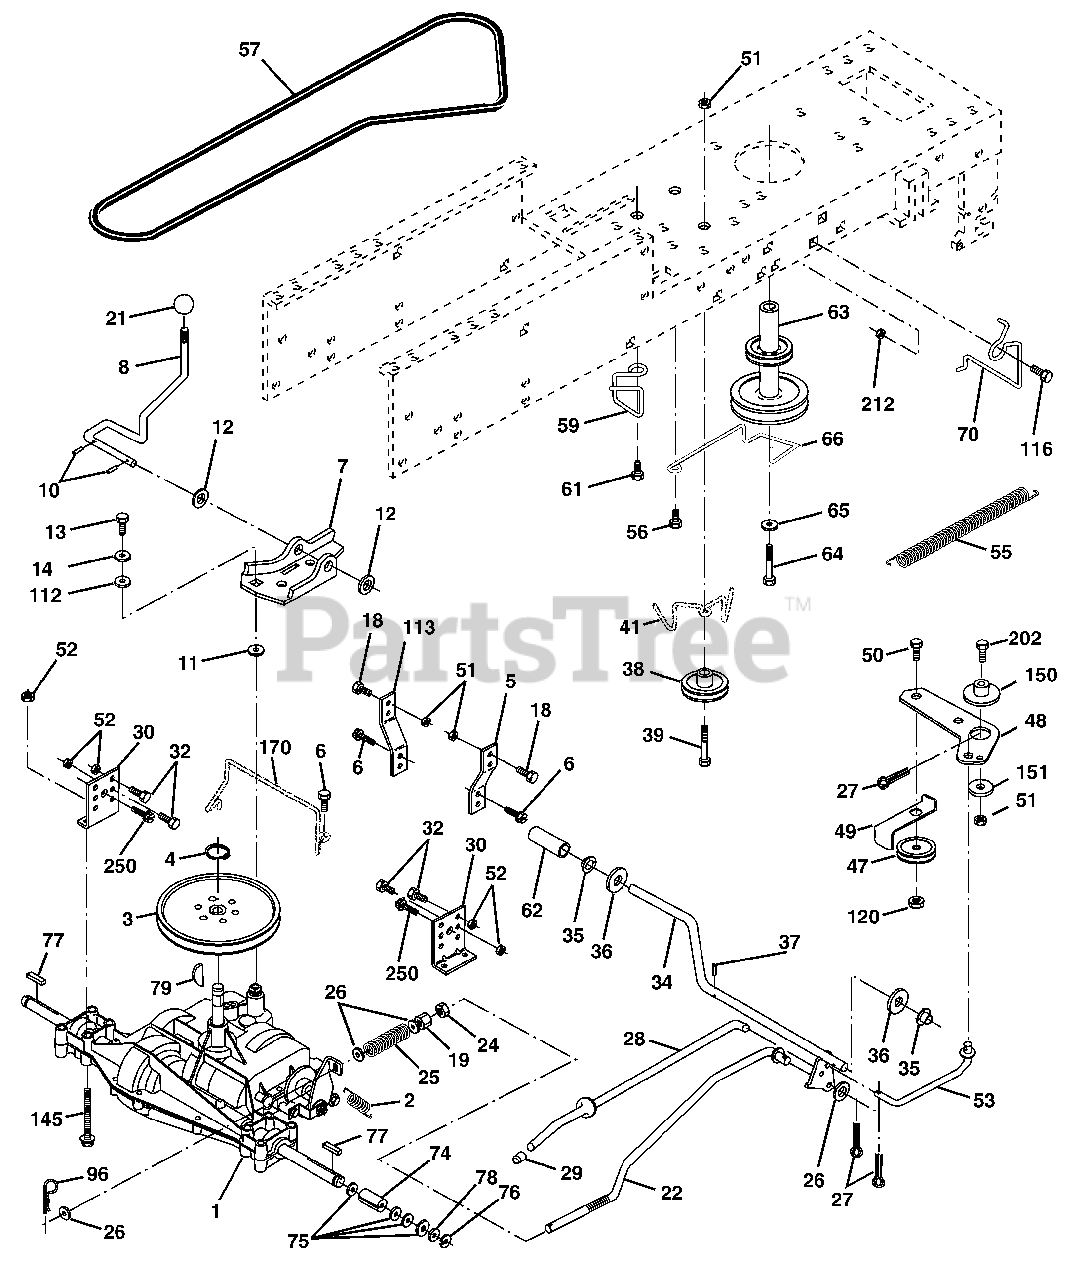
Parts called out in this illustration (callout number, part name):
2	Spring Extension Brake
3	Pulley Transaxle 18" tires
4	Ring Retainer # 5100-62
5	Strap Torque Rh Pnt Blk
6	Screw 5/16-18 X 3/4
7	Bracket T/A Saddle Shift
8	Rod Shifter Black(dana)
10	Pin,Cotter
11	Washer Plate Shf 388 Sq Hole
12	Washer 15/32 X 3/4 X 16ga
13	Bolt 1/4-28 UNF Gr. 8 W/Patch
14	Washer
18	Bolt Fin Hex 3/8-16 UNC x 1 Gr. 5
19	Nut
21	Knob Rd 1/2-13 Plstc Thds Blk
22	Rod Brake Lt
24	Nut
25	Spring Rod Brake 2 00 Zinc
26	Washer
27	Pin
28	Rod Brake Parking
29	Cap Parking Brake
30	Bracket Transmission
32	Bolt
34	Shaft Asm Pedal Foot
35	Bearing Nylon Blk 629 Id
36	Washer
37	Roll Pin
38	Pulley Idler Composite
39	Bolt Fin Hex 3/8-16 Unc x 3
41	Keeper Belt Idler
47	Pulley Idler V Groove Plastic
48	Bellcrank Clutch
49	Retainer Belt Style Spring
50	Bolt
51	Nut
52	Nut
53	Link Clutch 7 66
55	Spring Return Clutch 6 75
56	Screw 3/8-16 x 1-1/4
57	V-belt Ground Drive 95
59	Keeper Belt Chassis Span Ctr.
61	Screw 3/8-16 x .875
62	Cover Pedal Blk Round
63	Pulley Engine
64	Bolt, Hex 7/16-20 x 4 Grade 5
65	Washer, Lock, Hvy Hlcl Spring 7/16
66	Keeper Belt Engine Flproof
70	Guide Belt Dr Mower Rh
74	Spacer Axle
75	Washer 25/32 X 1 1/4 X 16 Ga
76	E Ring
77	Key Square 2 0 X 1845/ 1865
78	Washer 25/32 X 1 5/8 X 16ga
79	Key Woodruff
96	Retainer Spring 1"
112	Washer 9/32 X 3/4 X 10 Ga
113	Strap Torque Lh
116	Bolt, Rdhd Sqnk 3/8-16 x 1.00
120	Nut Lock Flg 3/8-16
145	Bolt Hex Flghd 5/16-18 x Gr. 5
150	Spacer Retainer
151	Washer 13/32 x 2 x 10 Ga.
170	Keeper Belt
202	Bolt
212	Nut Hex Flange Lock
250	Screw 3/8-16x3/4
